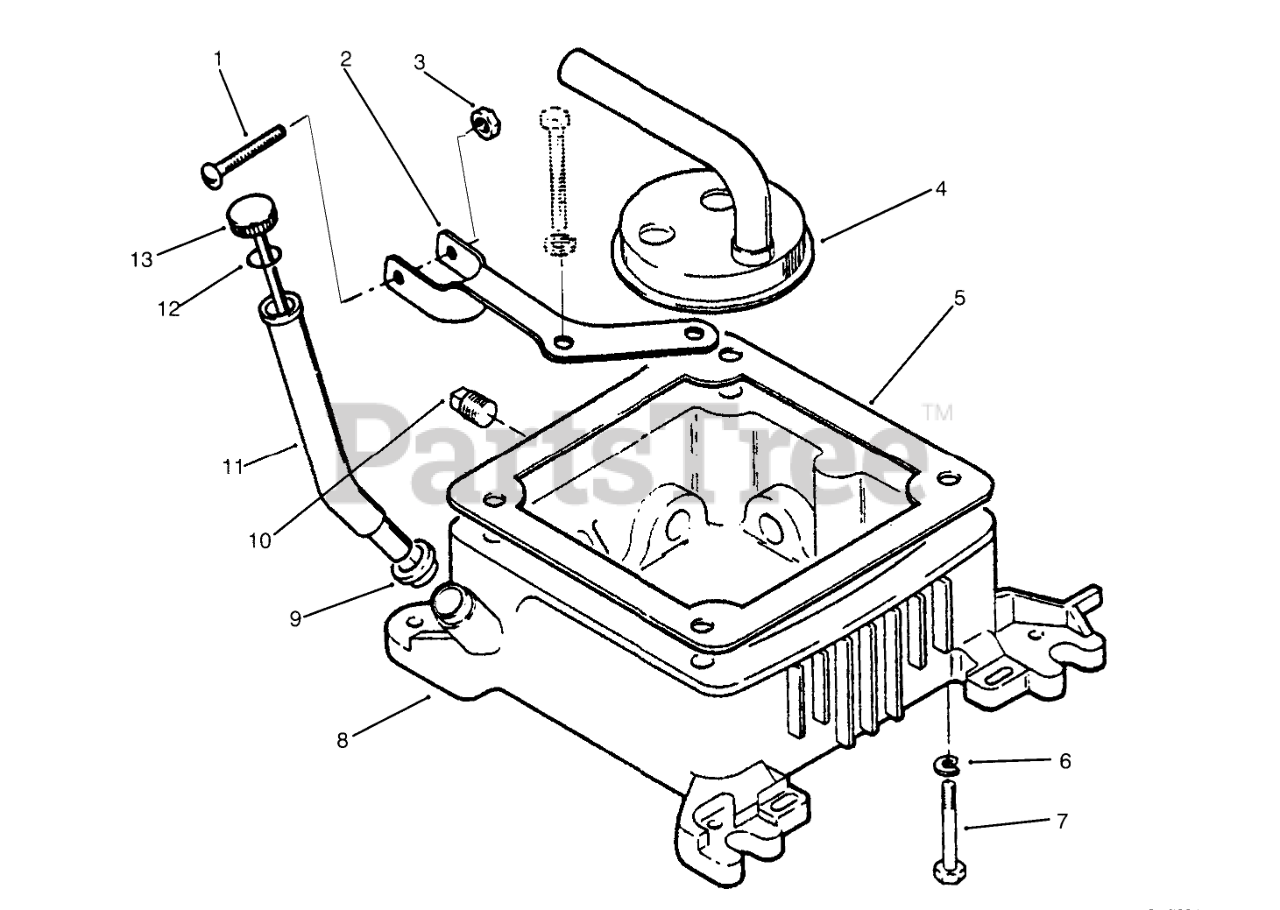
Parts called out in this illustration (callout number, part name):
1	SCREW - PAN HEAD
2	BRACKET-FILL TUBE
3	NUT - SPEED
4	OIL CUP ASM
5	GASKET
6	WASHER-FLAT
7	HHCS 3/8-16 X 3 3/4
8	Base-Oil (Incl. Ref. #10)
9	SEAL-OIL FILL TUBE
10	PLUG - SQUARE HEAD
11	Tube-Oil Fill
12	SEAL 0-RING
13	Cap & Indicator-Oil Fill (Incl. Ref. #12)
